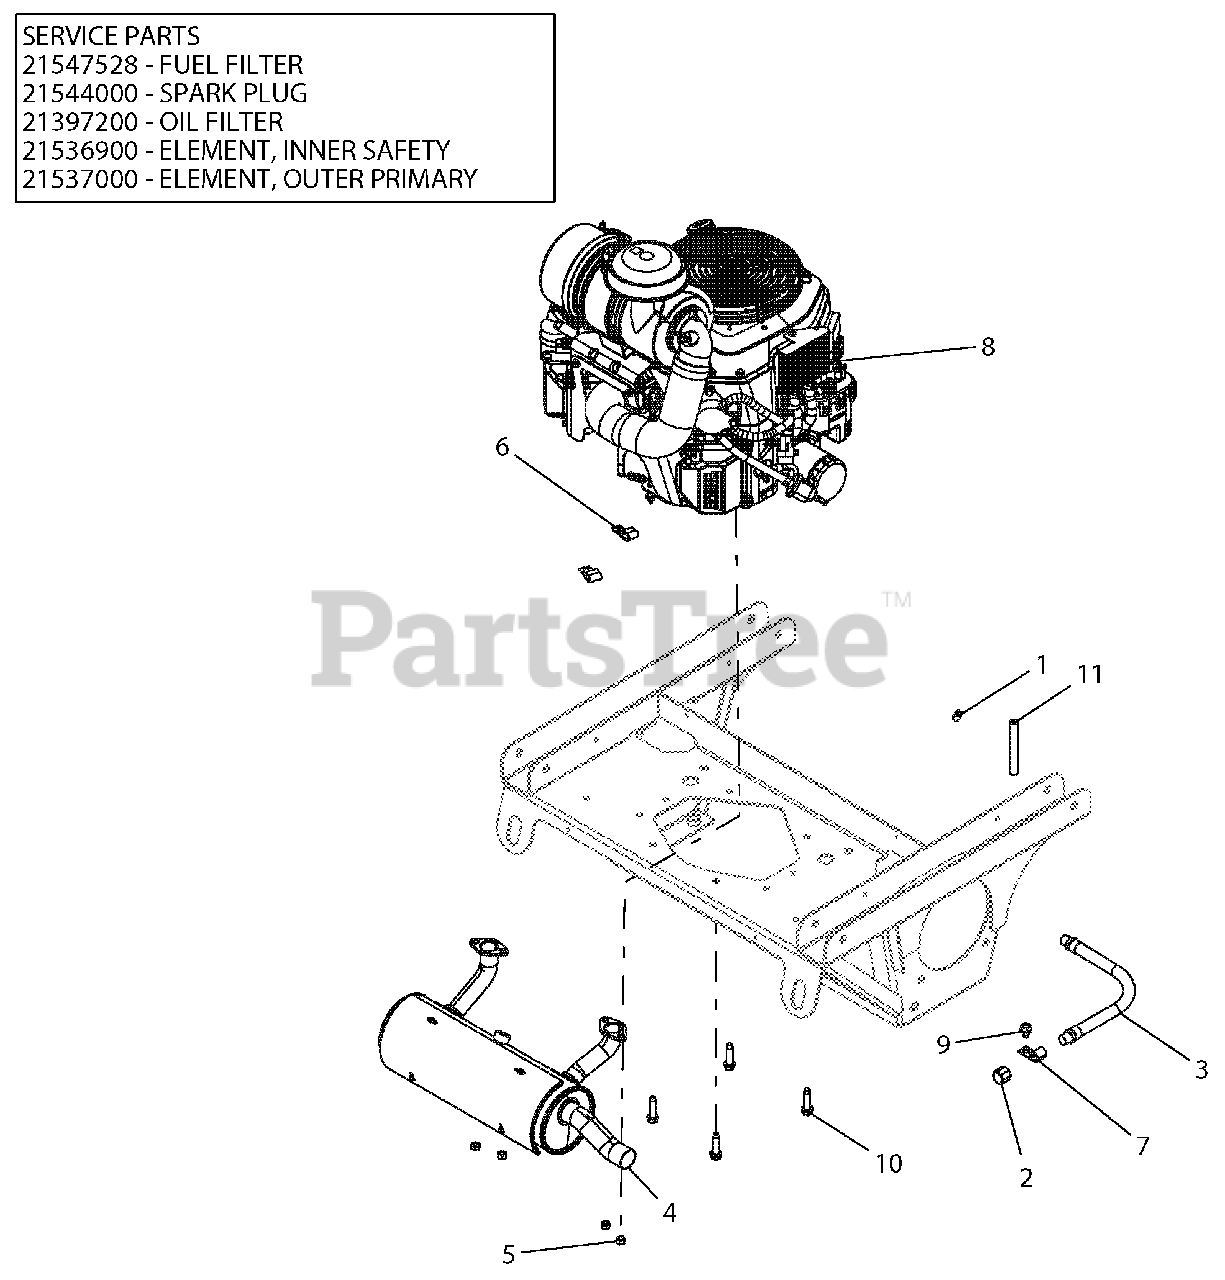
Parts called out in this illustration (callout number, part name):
1	CLAMP, FUEL LINE
2	PIPE, CAP 3/8 NPT FEMALE
3	HOSE, HYD .38-11-OK M6N0-M6N0
4	MUFFLER, KOHLER EFI
5	NUT-LK-TOP M8-1.25 YWZC
6	CLAMP, J
8	ENGINE, KOHLER EFI ECV749
9	SCR-TAP .38-16X.50 HWH TR YWZ
10	SCR-TAP .38-16X1.50 HWH TR YZ
11	.25 LOW-PERM GAS HOSE 22.00" LG - VALVE TO KOHLER EFI
